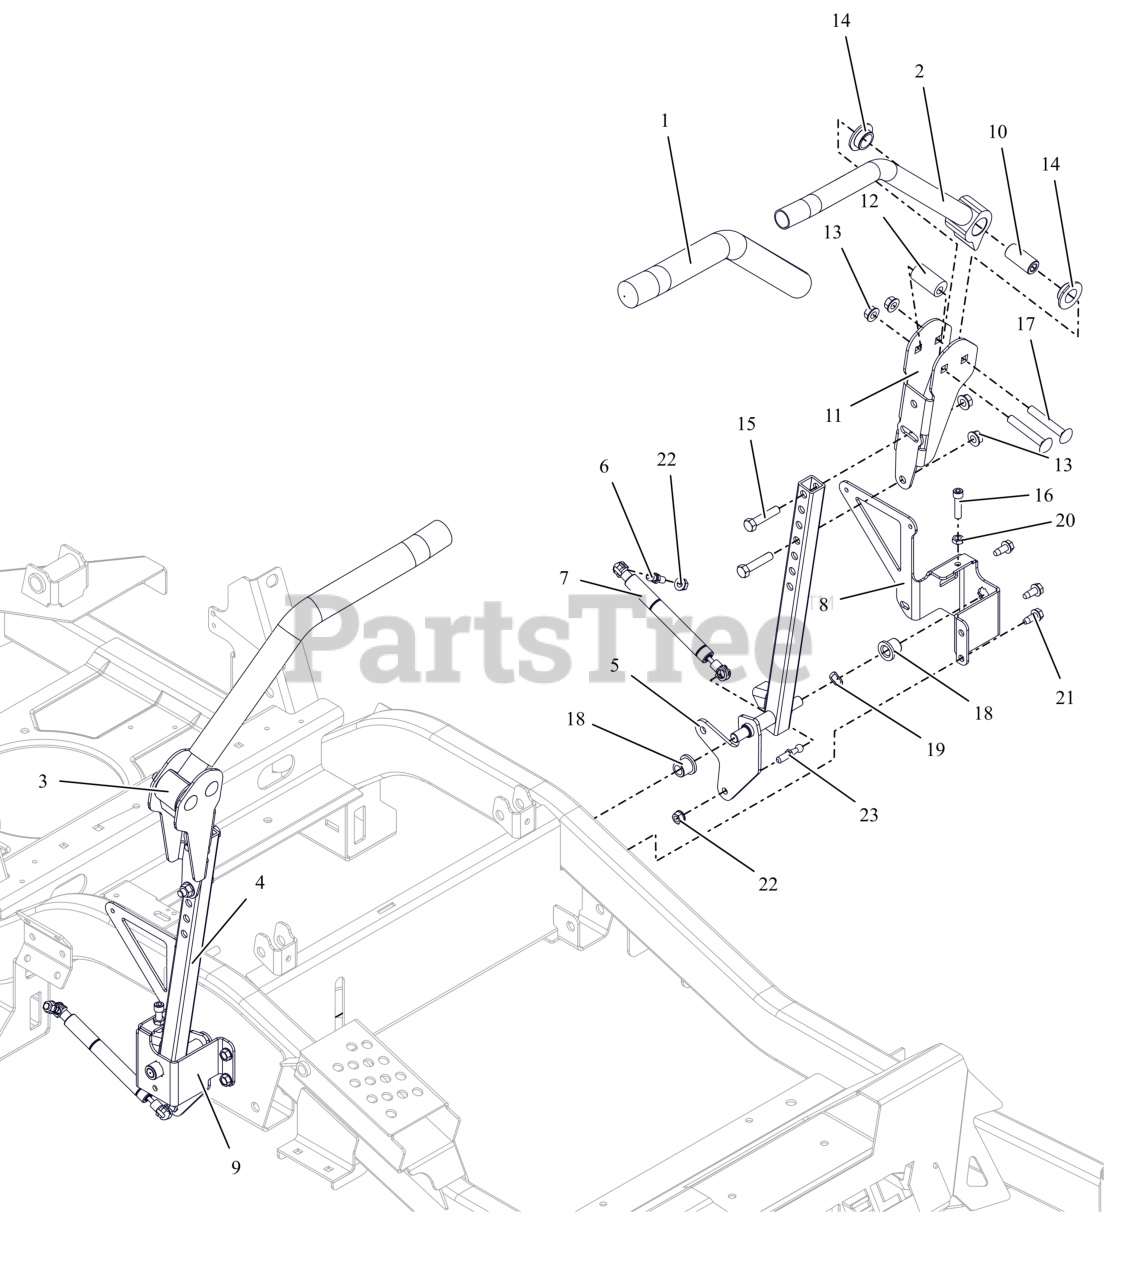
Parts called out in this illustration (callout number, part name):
1	GRIP, HANDLEBAR
2	WLDMT, CONTROL HANDLE (RED)
3	WLDMT, CONTROL HANDLE (RED)
4	WLDMT, STEERING RH (RED)
5	WLDMT, STEERING -LH (RED)
6	STUD- BALL
8	BRKT, STEERING ARM MOUNTING -LH (RED)
9	BRKT, STEERING ARM MOUNTING- RH (RED)
10	SPACER, STEERING ARM
11	BRKT, ADJ UPPER CONTROL ARM (RED)
12	BSHG, ECCENTRIC.406X.875X1.625
13	NUT-LK-TOP-FLG .38-16 ZC120
14	BSHG, FLANGED .762 X 1.48 X .44 IGLIDER
15	BLT, HEX .38-16X1.75 G5 ZCC
16	SCR, SKH .312-18X1.25 GR8 ZC120
17	BLT, RHSSN.38-16X2.50 G5 ZCC
18	BHSG-FLG .500X.750X.750X.125
19	WAVE WASHER .531X.781X.125FH
20	NUT-JAM .312-18 G2 ZCC
21	SCR,TAP .312-18X.75 HWH TR ZCC
22	NUT,LK-CTR-FLG .31-18 GF ZCC
23	STUD-BALL-THREADED
